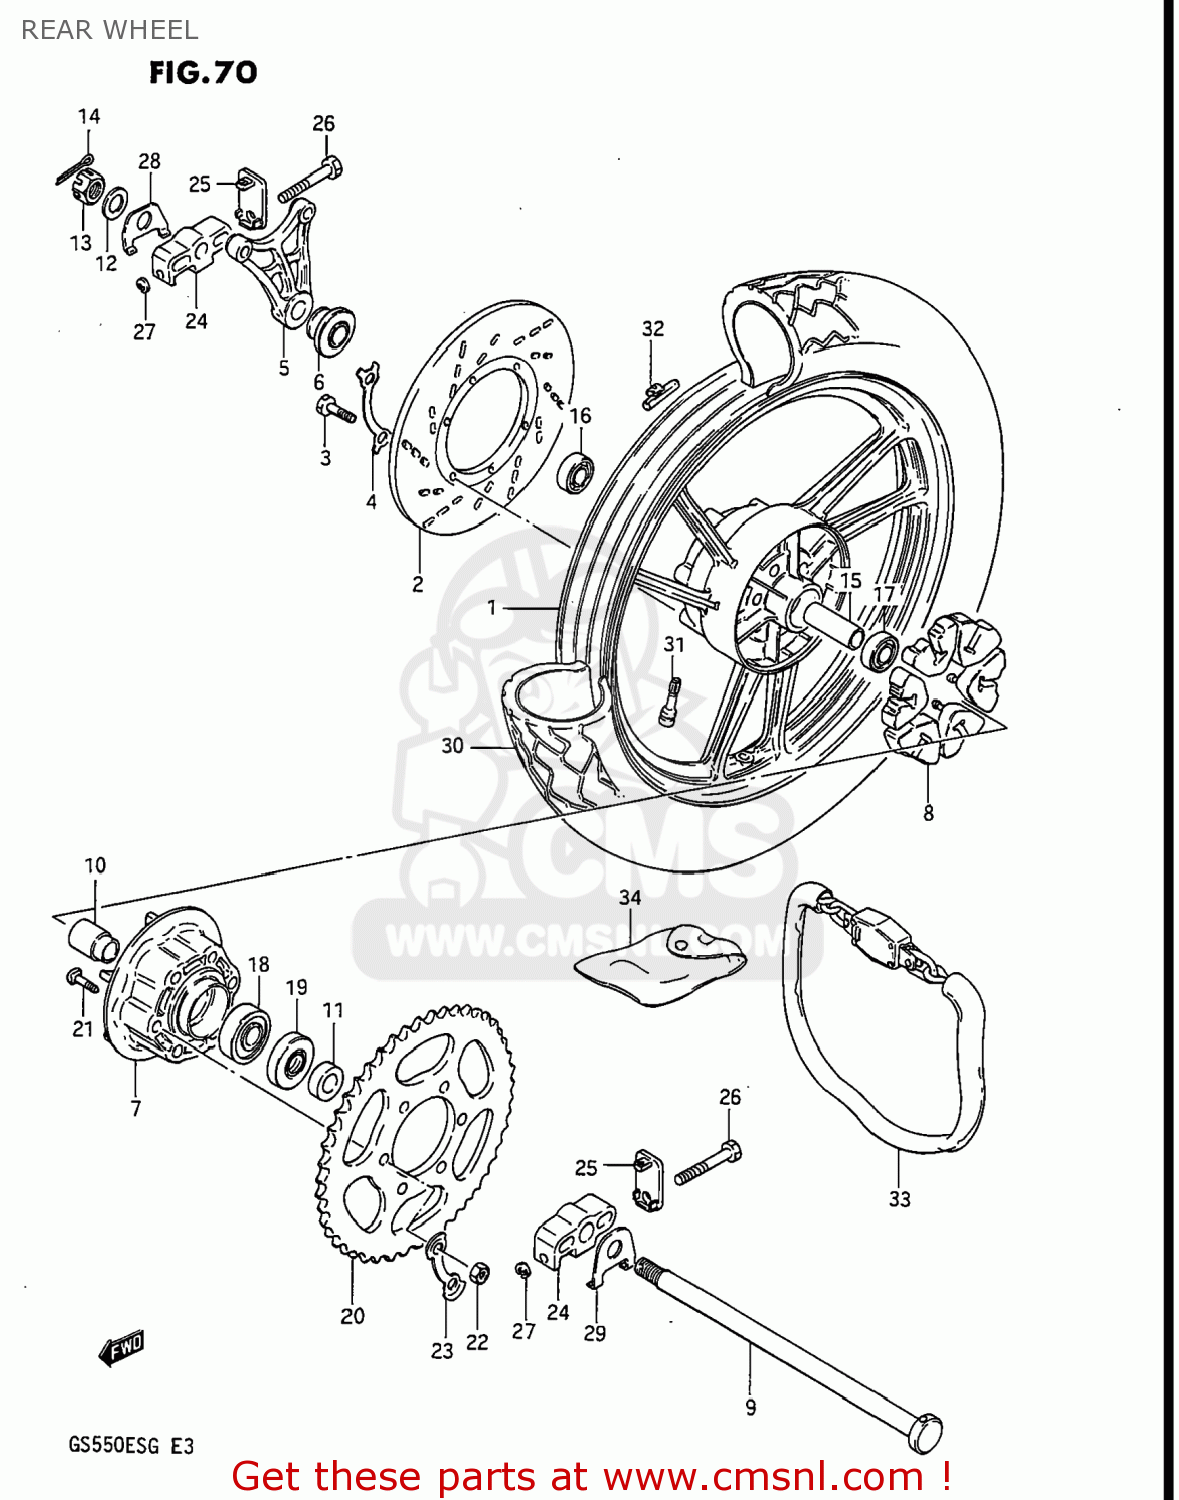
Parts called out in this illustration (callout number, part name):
1	WHEEL,REAR
2	DISC,REAR BRAKE
3	BOLT(8X25)
4	WASHER
5	BRACKET,RR,CALIPER
6	SPACER,REAR AXLE,RIGHT
7	DRUM,REAR SPROCKET MOUNT
8	ABSORBER,RR HUB SHOCK
9	AXLE,REAR
10	SPACER,REAR HUB BEARING
11	SPACER (17X30.5X13.5)
12	WASHER
13	NUT
14	PIN,COTTER
15	SPACER(17.5X25X81)
16	BEARING
17	BEARING
18	BEARING
19	SEAL,OIL(30.5X52X8)
20	SPROCKET,REAR
21	BOLT(10X35.5)
22	NUT
23	WASHER
24	BODY,CHAIN ADJUSTER
25	PLATE,CHAIN ADJUSTER
26	BOLT,CHAIN ADJUSTER
27	E RING
28	WASHER,CHAIN ADJUSTER RH
29	WASHER,CHAIN ADJUSTER
30	TIRE
31	VALVE,TIRE
32	BALANCER,WHEEL
33	CHAIN LOCK ASSY
34	BAG,CHAIN LOCK
